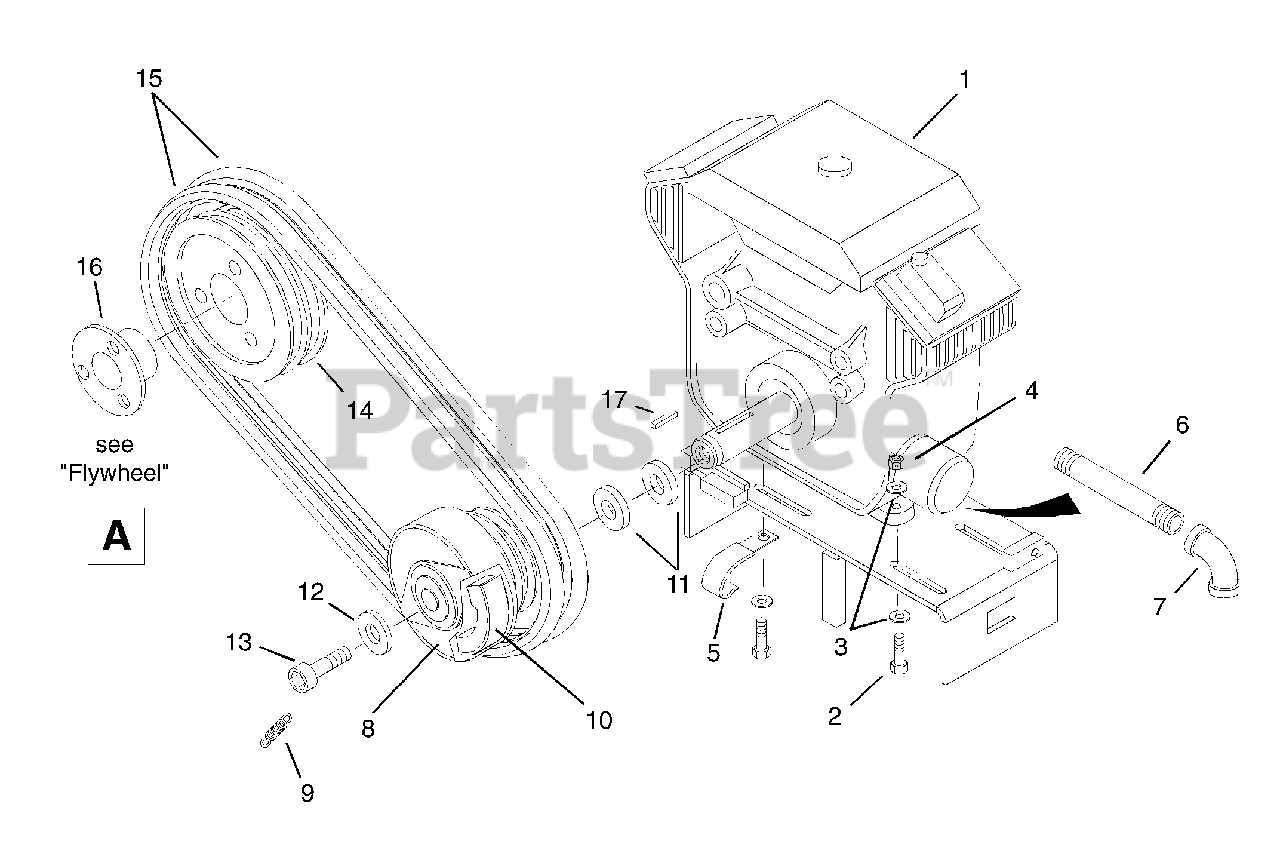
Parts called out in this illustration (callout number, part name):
1	25 HP Kohler Command PS-68548
2	Bolt-Hex .38-16 x 1.75 Grade 5
3	Washer-Flat-Steel .438 x 1.00 x .083
4	Nut-Locking-Center .38-16
5	Clamp-Line
6	Nipple .38 x 7.5
7	Elbow .375-18
8	Clutch 1.125 Bore
8	Clutch
9	Spring-Clutch
10	Shoe-Clutch
11	Shim 25 HP
11	Spacer
11	Bushing-Narrow Rim 14 GA 1-1/2 x 2-1/4
12	Washer 25 HP
12	Washer-Flat .640 x 1.81 x 2.50
13	Screw- Socket Head .43-20 x 1.50
13	Bolt-Socket Head SPL .62-18 x 1.75
15	V-Belt 23 HP Matched Set
16	Bushing SK x 1-1/2
17	Key-Square .25 x 2.50 x .25
17	Key-Straight .38 x 2.75 x .38
